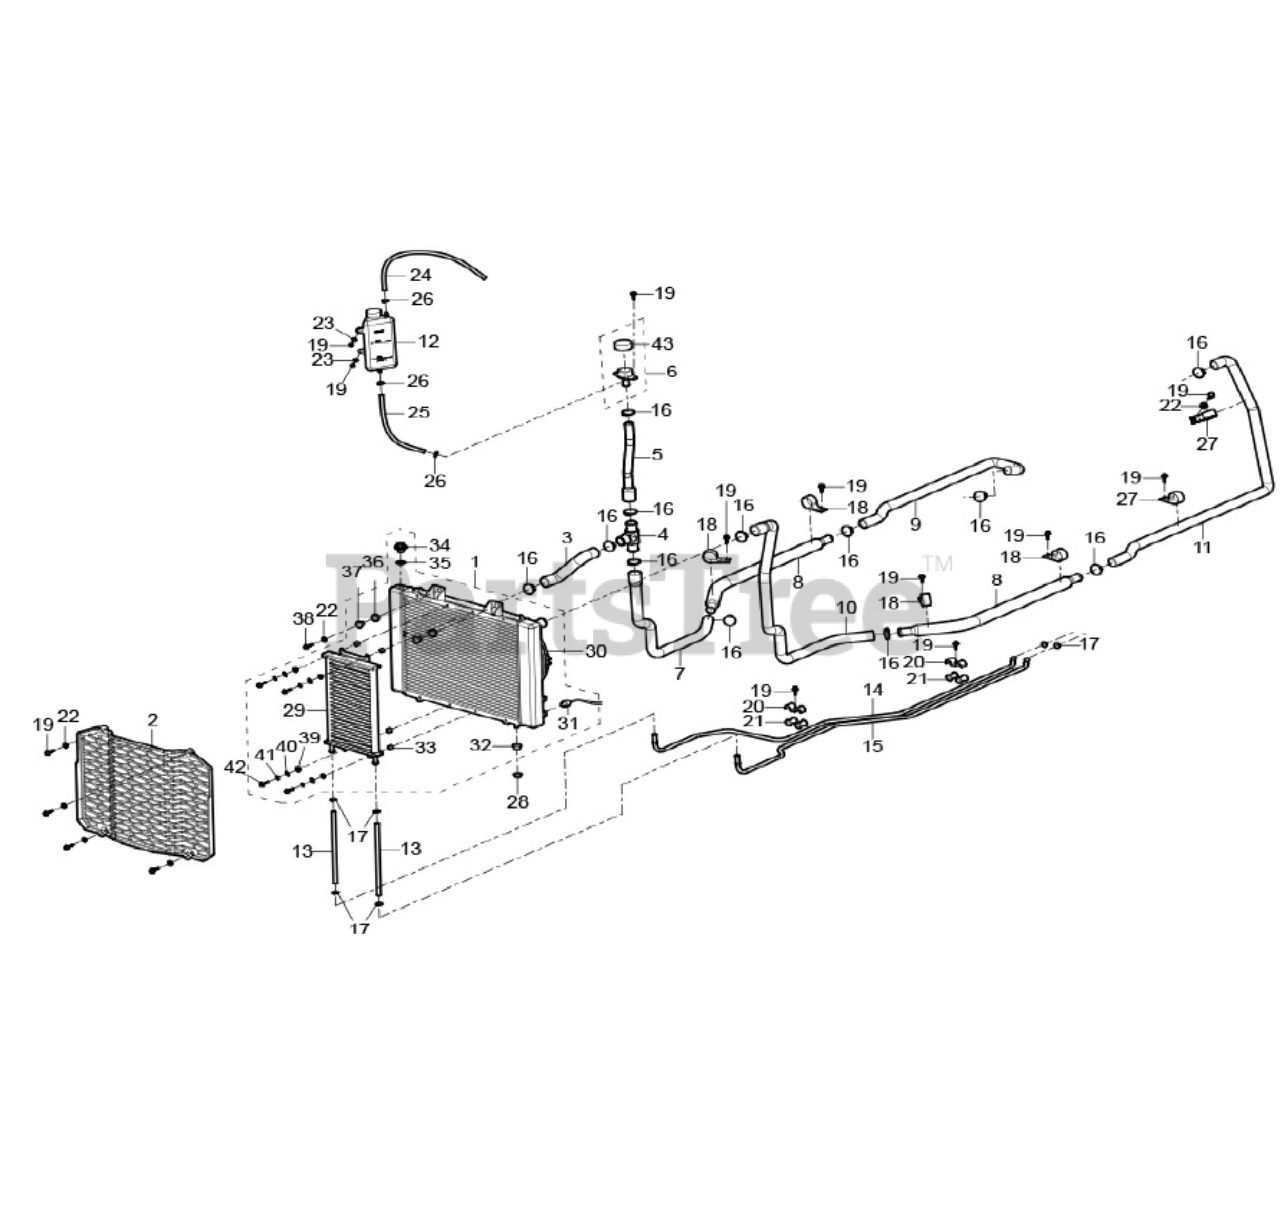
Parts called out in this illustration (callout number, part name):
2	RADIATOR COVER
3	HOSE - WATER INLET - RADIATOR
4	TEE PIPE COUPLING
5	RADIATOR WATER INLET HOSE IV
6	FILTER NECK
7	RADIATOR HOSE WATER INLET II
8	HOSE - ALUMINIUM?
9	RADIATOR HOSE WATER INLET ?
10	RADIATOR HOSE WATER OUTLET II
11	RADIATOR HOSE WATER OUTLET ?
12	TANK SURGE ASSEMBLY
13	HOSE - RUBBER?
14	HOSE - METAL?
15	HOSE - METALII
16	Screw Clip D
17	Lock Clamp A
18	Water Pipe attach clamp III
19	Hexagon Flange Bolt M6x16
20	fixing pipe clamp(M type)
21	fuel line rubber
22	HExAGON FLANGE HEAD NUT M6
23	Flanger bush 5.1x 8x5
24	Exhalent siphon for auxiliary kettle
25	water inlet for auxiliary kettle
26	Spring clamp C
27	CLIP - WATER HOSEII
29	OIL COOLER
30	WATER TANK
31	WATER TEMP SENSOR
33	WATER TANK CUSHION
35	O-RING 9X1.8
36	WATER TANK BRACKET
37	WATER TANK BRACKET BUSHINGS
38	HEXAGON FLANGE BOLT M6X25
39	NUT HEXAGON FLANGE HEAD M6
40	PLAIN WASHER 6
41	SPRING WAHSER 6
42	HEXAGON BOLT M6X25
43	WATER TANK COVER
